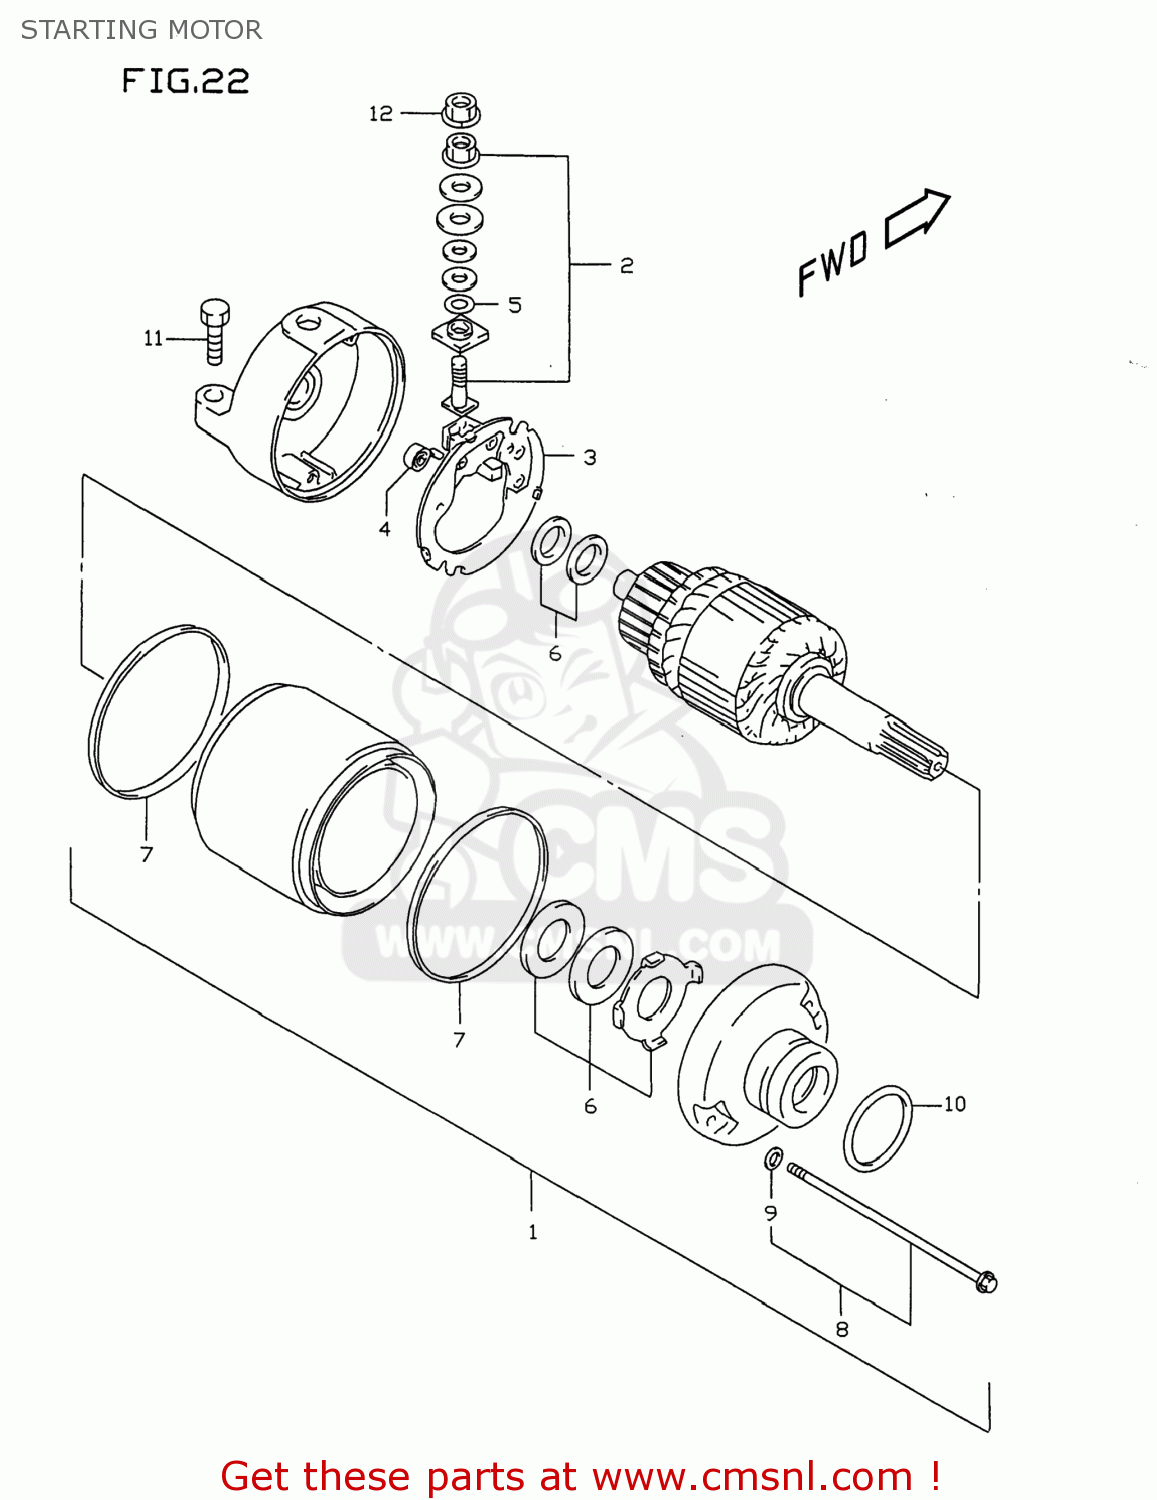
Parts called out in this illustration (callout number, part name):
1	MOTOR ASSEMBLY,STARTING
2	BRUSH TERMINAL SET
3	BRUSH HOLDER SET
4	SPRING,BRUSH
5	O RING
6	SHIM SET,STARTING MOTOR
7	O RING
8	BOLT
9	O RING
10	O RING(D:3,ID:24.5)
11	SCREW (6X25)
12	NUT
